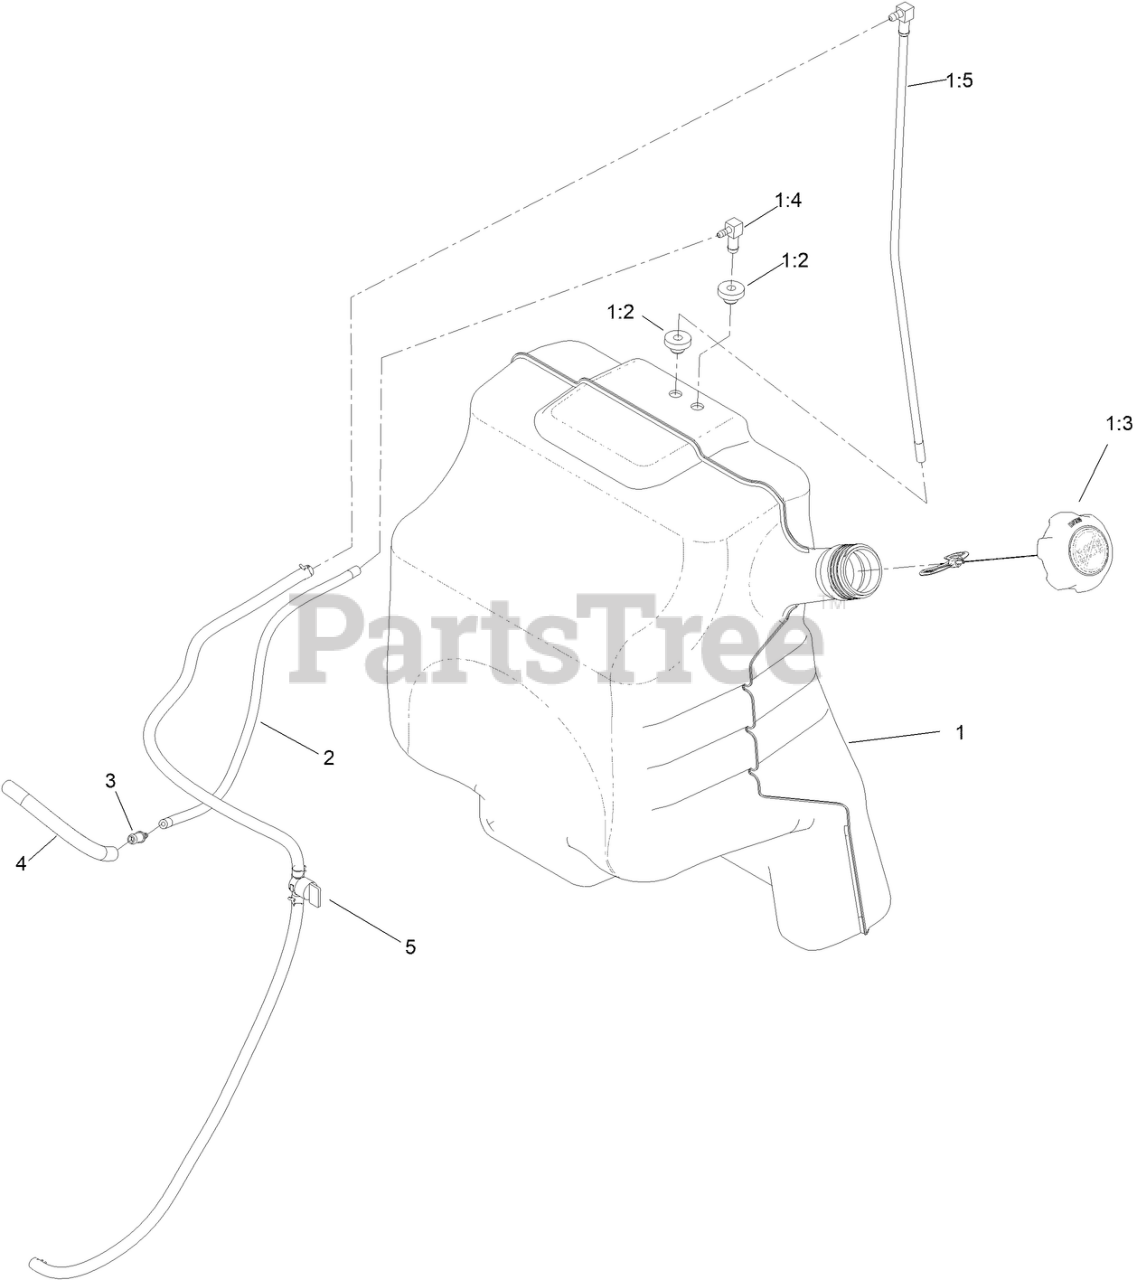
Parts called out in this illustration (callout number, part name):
1	FUEL TANK ASM
1:2	BUSHING
1:3	CAP-FUEL
1:4	FITTING-ELBOW, 90 DEG
1:5	ASM, TUBE-FUEL
2	HOSE-FUEL
3	BARB-FUEL
4	HOSE-FUEL
5	FUEL LINE ASM
